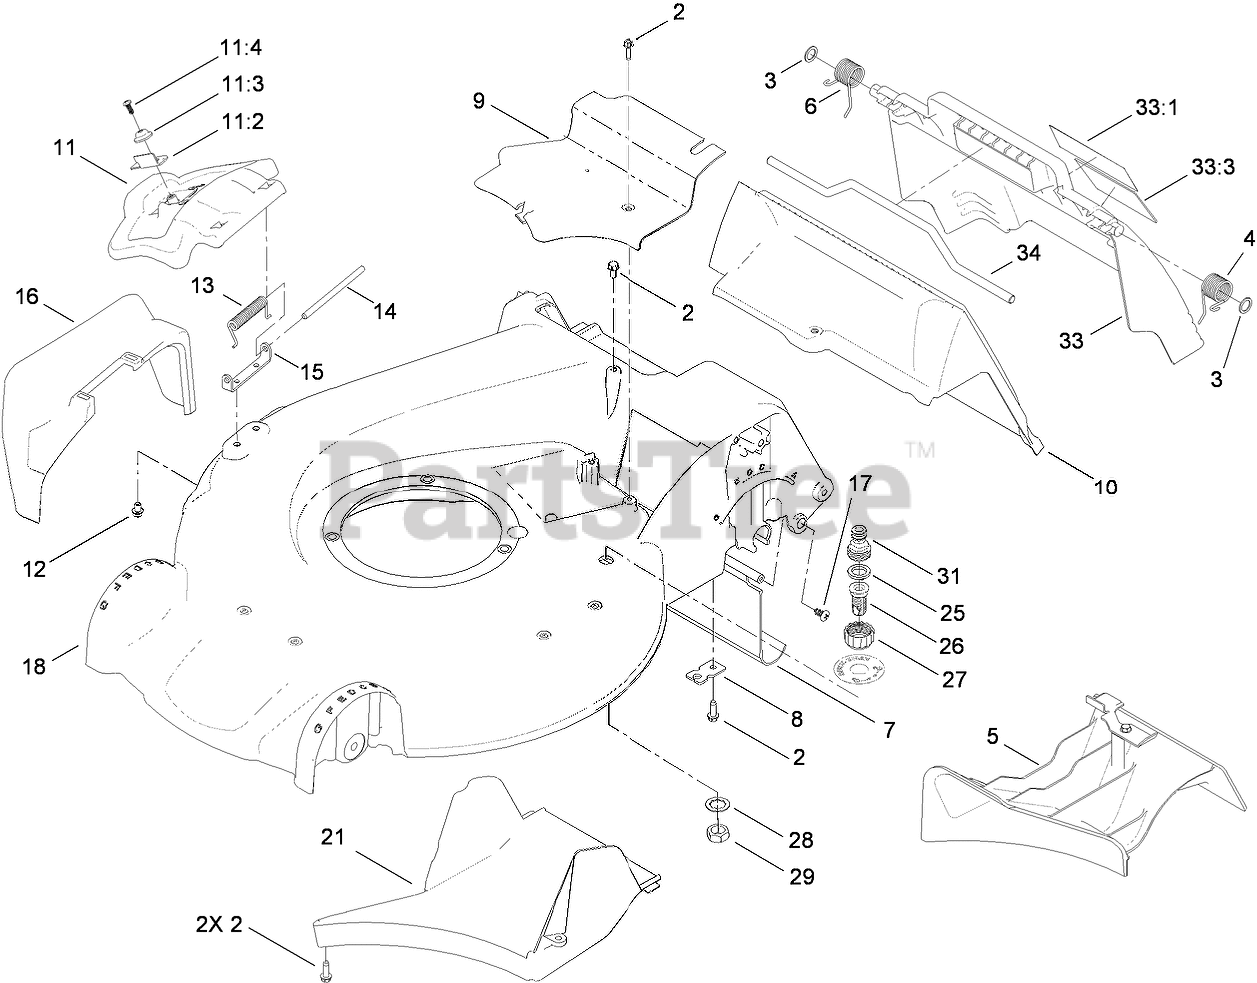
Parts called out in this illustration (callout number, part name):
2	SCREW-HWHTF
3	WASHER-NYLON
4	SPRING-TORSION
5	MULCH PLUG ASM
6	SPRING-TORSION
7	SHIELD-TRAILING
8	BRACKET-CABLE, TRACTION
9	COVER-BELT
11	DISCHARGE DOOR ASM
11:2	LATCH-DOOR
11:3	CAP-DOOR
11:4	SCREW-PLASTITE
12	SCREW-HWH
13	SPRING-TORSION
14	ROD-COVER
15	BRACKET-COVER
16	CHUTE-DISCHARGE, SIDE
17	SCREW-PTH
18	HOUSING ASM
21	TUNNEL-DISCHARGE
25	WASHER-SEAL, WASHOUT PORT
26	PORT-WASHOUT
27	COUPLING-HOSE, WASHOUT PORT
28	WASHER-TOOTH, INTERNAL
29	NUT-JAM
31	ADAPTER-CONNECT, QUICK
33	REAR DOOR ASM
33:1	DECAL-WARNING
33:3	DECAL-WARNING
34	ROD-DEFLECTOR
